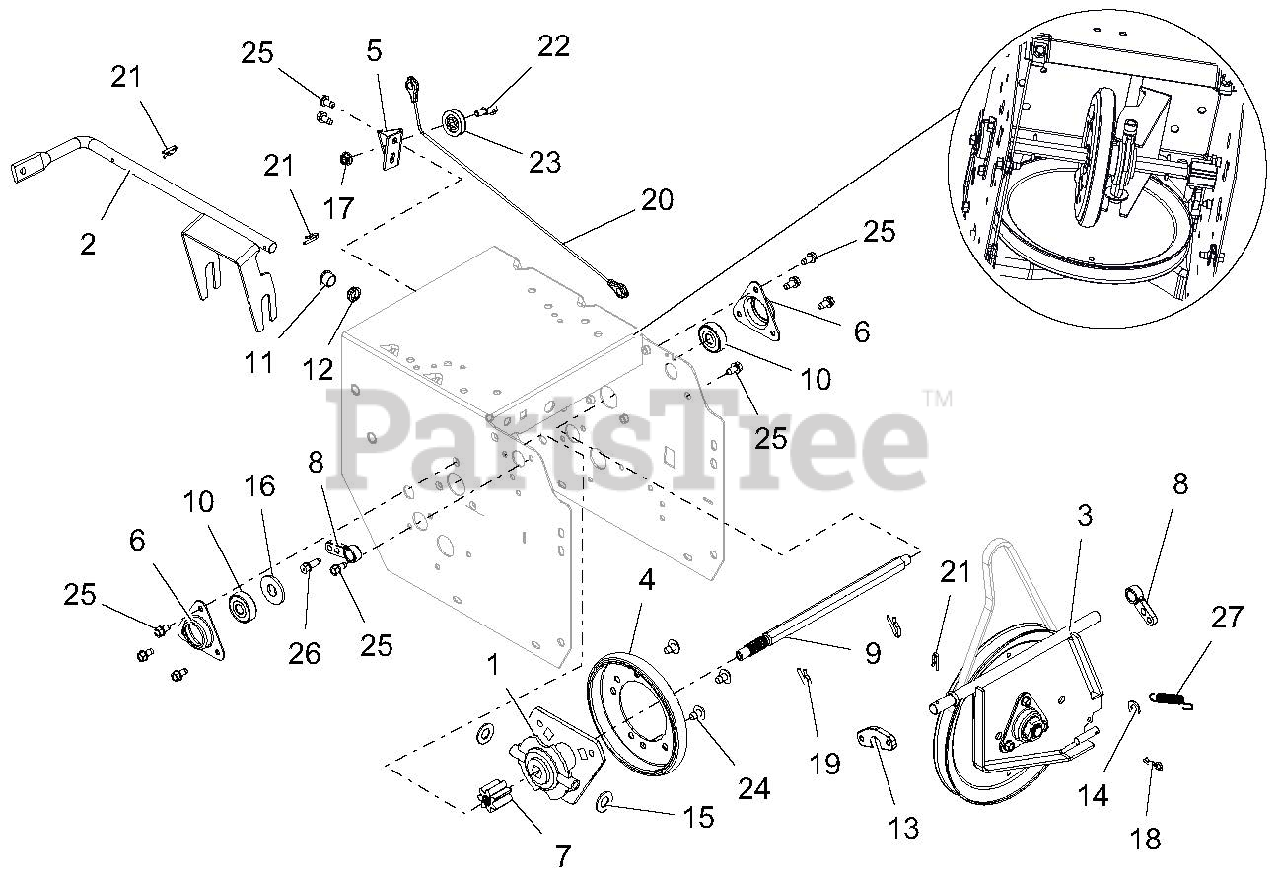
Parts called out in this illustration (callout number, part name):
1	CARRIER, DRIVE DISK
2	WELDMENT, SHIFT FORK
3	PLATE, SWING - ASSEMBLY
4	FRICTION, DISC
5	BRACKET, CABLE PULLEY
6	FLANGE, BEARING
7	GEAR, PINION, 7 TOOTH W/SPLINE
8	SUPPORT BUSHING, SWING GATE
9	SHAFT, HEX W/SPLINE
10	BRG-BALL .437X1.375X.437
11	BUSHING, POLYLINER-.50 SPLIT
12	BUSHING, POLYLINER-.50 SNAPIN
13	SPACER, SWING GATE
14	@WSHR-FL-STL.344X.688X.065YWZC
15	WSHR-FL-STL .505X1.00X.062YWZC
16	@WSHR-FL-STL.563X1.38X.109YWZC
17	@NUT-LK-CTR-FLG .25-20 YWZC
18	PIN-HAIR INT .08X.18X1.18 YWZC
19	PIN, SPRING CLIP
20	CABLE, LOWER TRACTION (DELUXE)
21	CLIP, SPRING
22	BOLT, SHLDR-.375X.375X.25-20
23	PULLEY, CABLE
24	SCR-TAP SERRDHDTX .31-18X.50BP
25	SCR-TAP .25-20X.50 HWH TR YWZ
26	SCR-TAP-PM .25-20X.75 TR YWZ
27	SPRING, EXT. .043X.438X1.64
